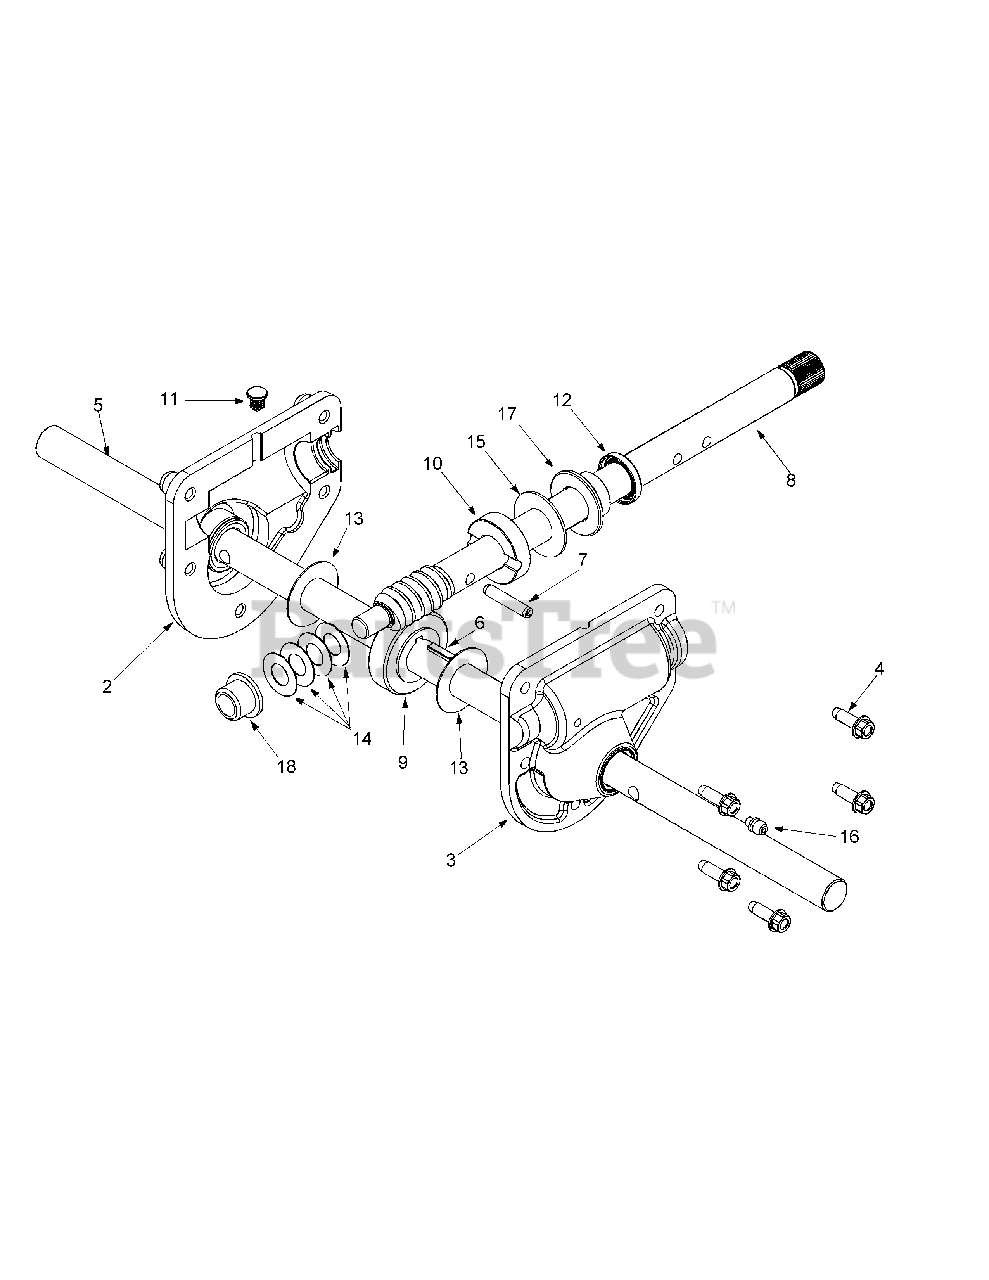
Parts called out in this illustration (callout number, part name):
1	Auger Gearbox Ass’y Comp.
2	Housing Assembly, RH
3	Housing Assembly, LH
4	Screw, 1/4-20 x .75
5	26" Auger Axle
6	Hi-Pro Key
7	Spirol Pin
8	Worm Shaft .75
9	Worm Gear 20T
10	Thrust .75 x .415
11	Plug 1/4 x .437
12	Oil Seal .75 x 1.73
13	Fl-Wash. .760 x 1.5
14	Fl-Wash. .508 x 1.0
15	Fl-Wash. .76 x 1.50
16	Lube Fitting 3/16 Drive
17	Flange Bearing
18	Flange Bearing
